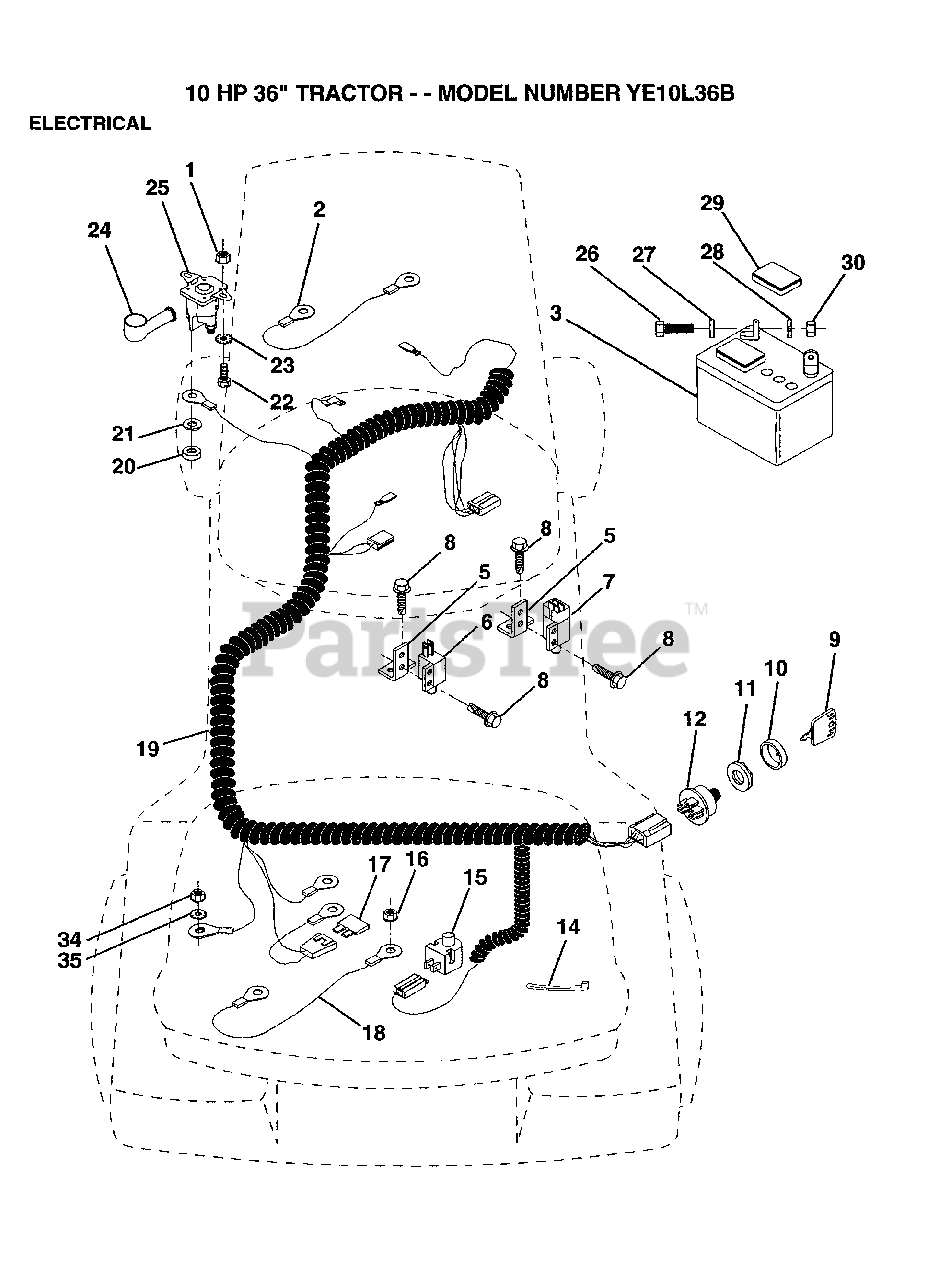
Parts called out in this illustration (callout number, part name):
1	NUT
2	CABLE ASM.
5	BRACKET LT
6	SWITCH-INTER. GT
7	SWITCH INTERLOCKT
8	SCREW
9	KEY
11	NUT IGNITION
14	WIRE TIE
15	SWITCH SEAT
17	FUSE HYT
18	CABLE ASSY
20	NUT
22	BOLT
26	BOLT LT
27	WASHER
28	LOCKWASHER
29	"CAP,BATTERY "
34	NUT
35	LOCKWASHER
